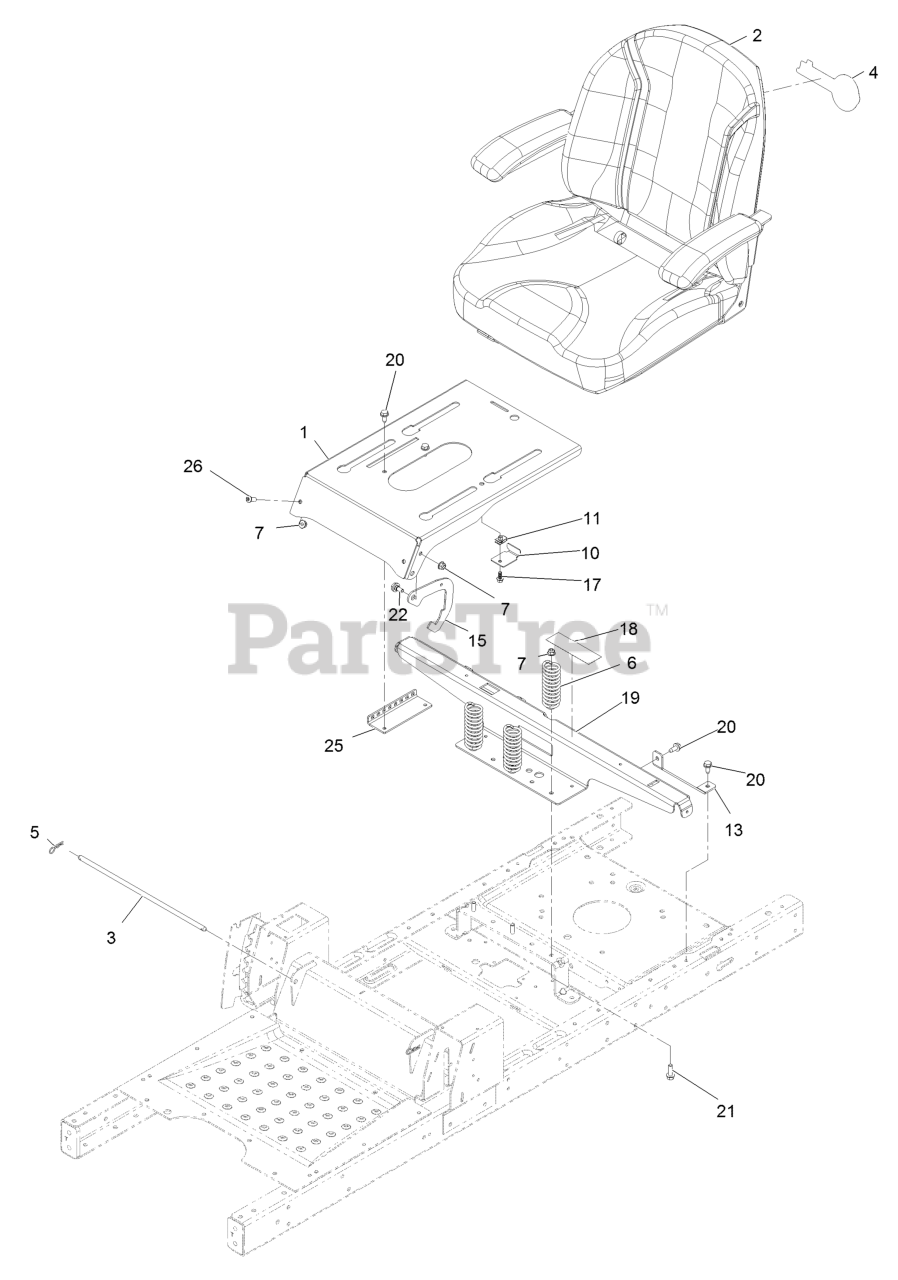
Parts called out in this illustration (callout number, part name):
2	SEAT ASM, EXMARK
3	ROD-PIVOT, NARROW
4	DECAL-EXMARK LOGO
5	PIN-COTTER
6	SPRING-COMPRESSION
7	NUT-HF, NI
10	BRACKET-STOP, SEAT
11	Nut-Retainer-Panel 1/4-20
13	SUPPORT-TANK, REAR
15	LATCH-SEAT
17	SCREW-HHF
18	DECAL-SERVICE, CE
19	SUPPORT-POD
20	Screw-HWH 5/16-18 X 3/4 Tf
21	SCREW-HHF
22	BOLT-SHOULDER,HFH
25	BRACKET-LATCH, SEAT
26	SCREW-HSBH
